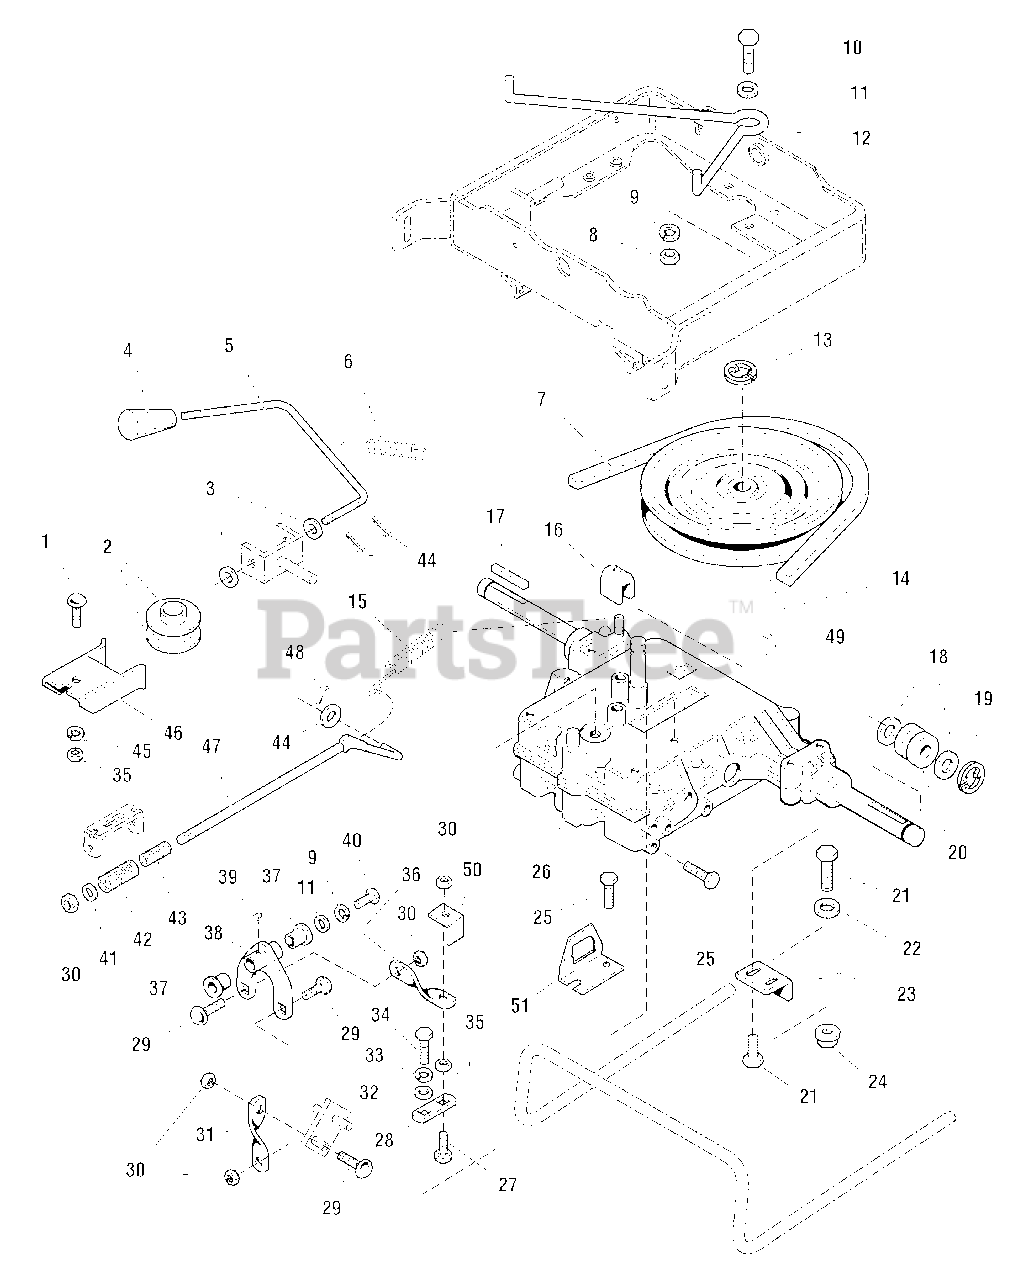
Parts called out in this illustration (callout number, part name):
1	CARRIAGE BOLT, 5/16-18 x 3/4
6	SPRING, Extension
8	NUT, Hex 3/8-16
9	LOCKWASHER, 3/8
10	CAPSCREW, Hex Head, 3/8-16 x 1-1/4
11	WASHER
12	GUIDE, Belt
13	RING, Shaft
14	PULLEY & HUB ASSEMBLY
15	SPRING, Extension
17	KEY
19	RING, Shaft
21	SCREW, Hex Washer Head Taptite, 5/16-18 x 2-1/2
22	WASHER
23	ANCHOR, Torsion Bar
24	NUT, Hex Head Whiz Lock, 5/16-18
25	SCREW, Hex Washer Head Taptite, 5/16-18 x 5/8
26	TRANSMISSION ASSEMBLY
27	CARRIAGE BOLT, 5/16-18 x 1-1/2
28	LEVER, Shift
29	CARRIAGE BOLT, 5/16-18 x 1-1/4
30	NUT, Hex Lock, 5/16-18
31	LINK, Shift Upper
32	WASHER
33	LOCKWASHER, 1/4
34	CAPSCREW, Hex Head, 1/4-28 x 5/8
35	NUT, Hex, 5/16-18
36	LINK, Shift, Lower
38	BELLCRANK ASSEMBLY w/Bushings (Incl. Ref ??)
39	FITTING, Grease
40	CAPSCREW, Hex Head, 3/8-16 x 3/4
42	SPRING-Compression
43	SPRING-Compression
44	PIN, Cotter
45	LOCKWASHER, 5/16
46	GUARD, Belt
48	PIN, Cotter
49	KEY, Woodruff #9
50	SWITCH, Actuator
51	SWITCH, Mounting Bracket
